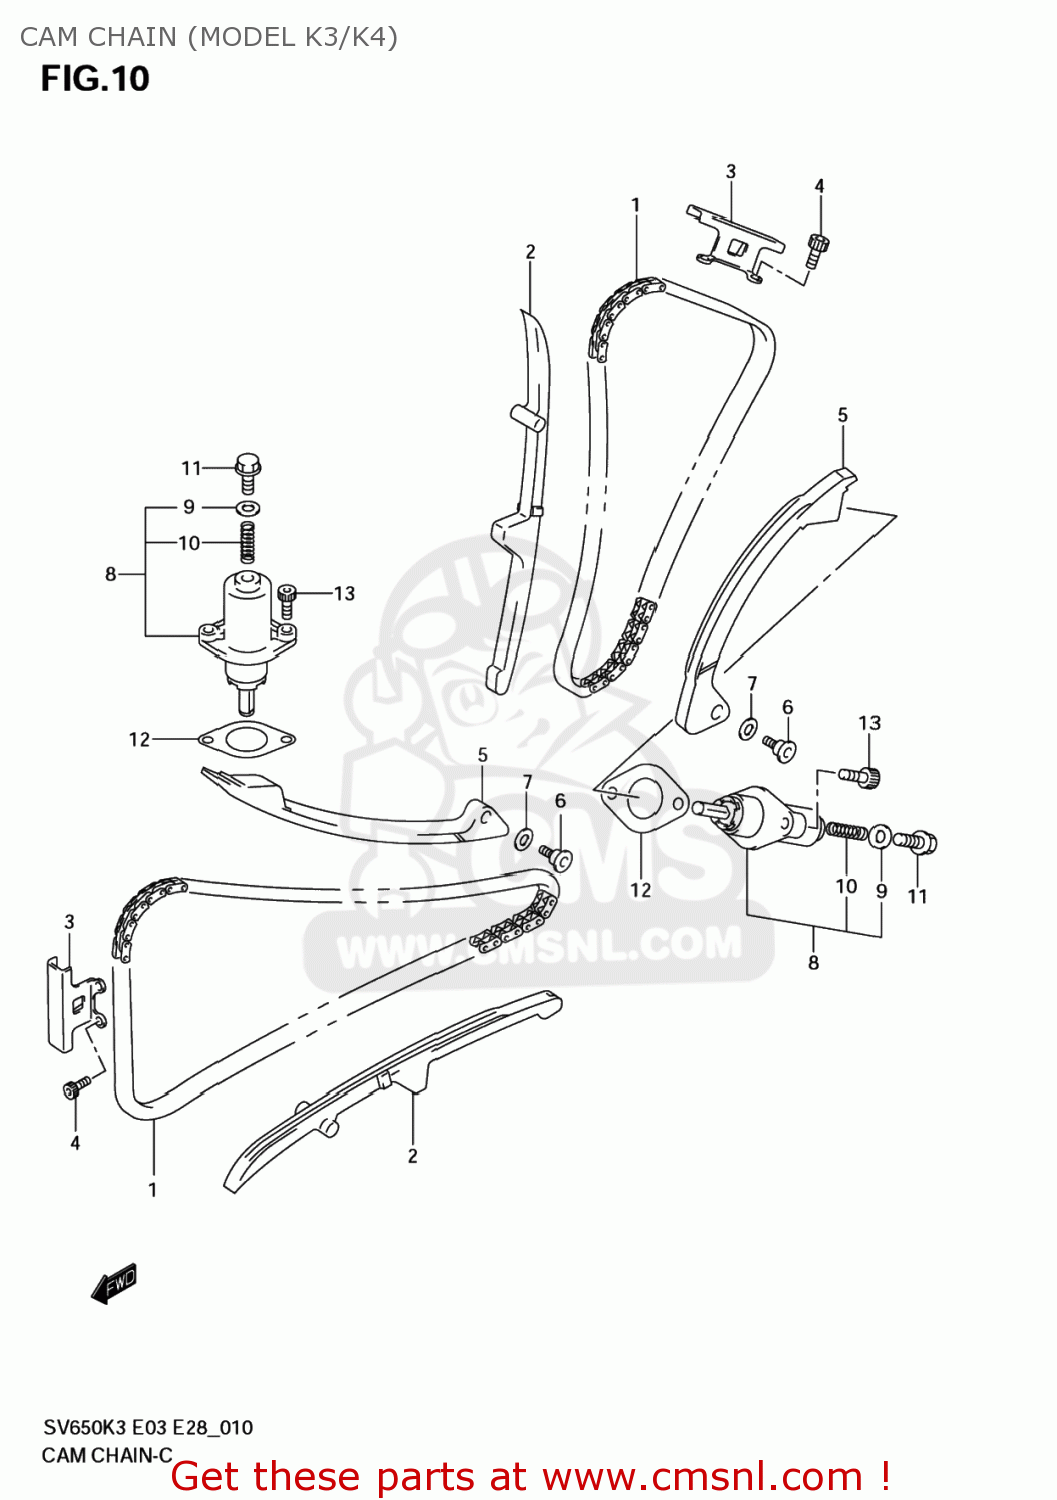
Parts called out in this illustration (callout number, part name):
1	CHAIN COMP,CAMSHAFT DRIVE
2	GUIDE,CAM CHAIN NO.1
3	GUIDE,CAM CHAIN NO.2
4	BOLT,STRANGER
5	TENSIONER,CAM CHAIN
6	BOLT,CAM CHAIN TENSIONER
7	WASHER
8	ADJUSTER ASSY,TENSIONER
9	GASKET,TENSIONER ADJUSTER (NAS)
10	SPRING
11	PLUG,TENSIONER ADJUSTER
12	GASKET,TENSIONER ADJUSTER (NAS)
13	BOLT,CL.COVER
